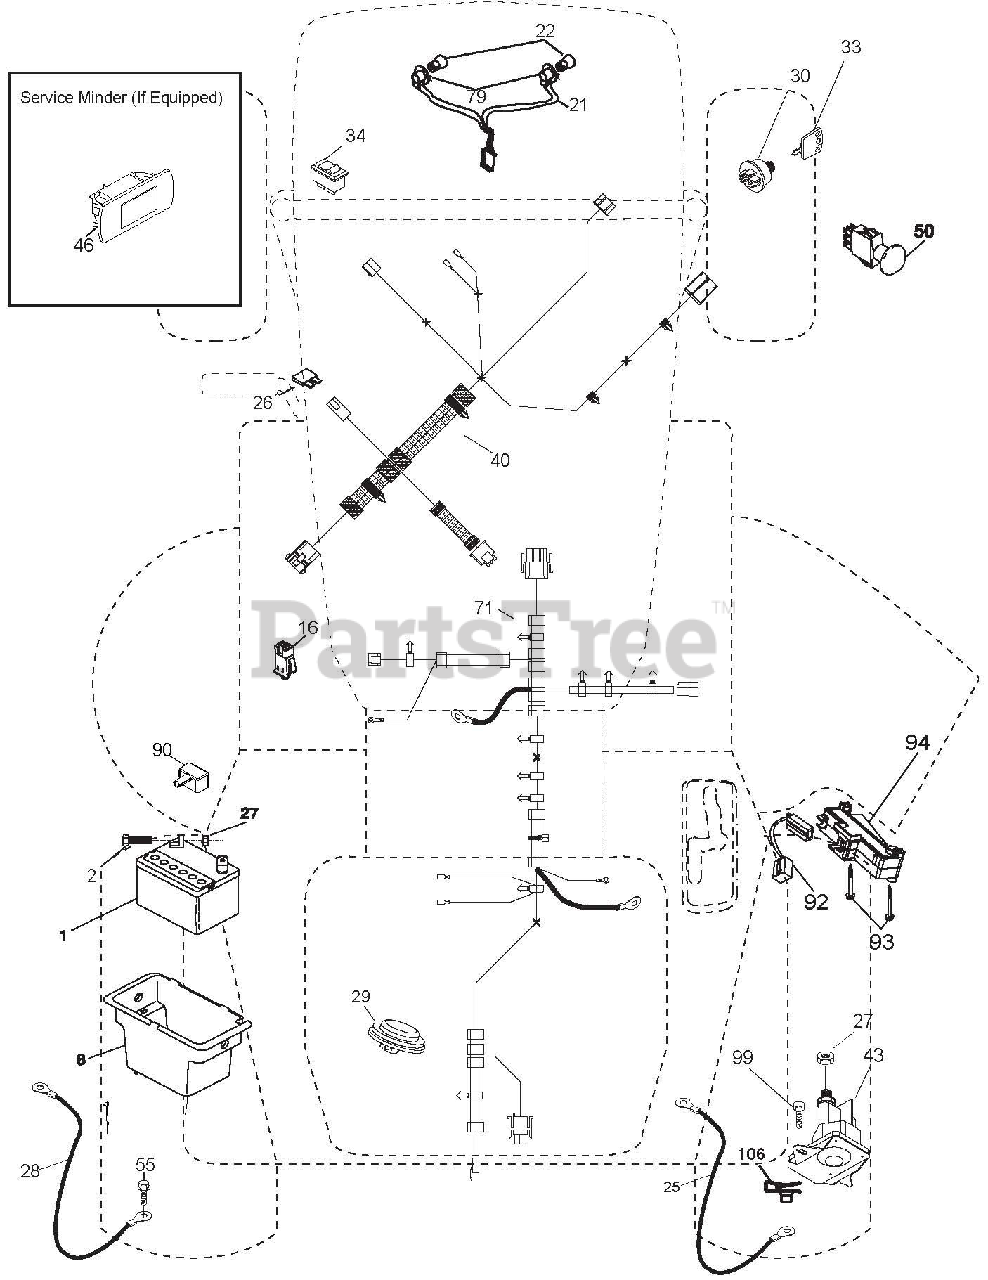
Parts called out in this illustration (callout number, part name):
1	BATTERY.12.VOLT.28.AMP.WET
2	BOLT.HEX.HD.1/4-20UNC X 3/4
8	BOX.BATTERY.MNT.REAR.LT.TEX.BL
16	SWITCH.INTERLOCK.NONO.GRAY
21	HARNESS ASM.LIGHT.22"(4152J)
22	BULB.LIGHT.#1156
25	CABLE STARTER 6 G4. BL/RED14.5
26	FUSE.20 AMP.
27	Nut, Keps Hex 1/4-20 unc
28	CABLE.BLACK.22"REAR BATT.TEX
29	SWITCH.SEAT.DELTA.OPC.9LB.
30	SWITCH.IGN.DLTA.P-IN.ROS
33	KEY/CHAIN.BLISTER PACK.GEN.USA
34	SWITCH.LIGHT/RESET.B/B/RED.
40	HARNESS IGN ELEC RELAY
43	SOLENOID.W/BRASS PLUNGER.2005
46	HOUR METER
50	SWITCH.PTO.8 TERMINAL.BLACK
55	SCREW.5/16-18X3/4.SMGML.TAP/R
71	HARNESS.IGN.CHASSIS.TEX
79	SOCKET ASM.BULB.TWISTLOCK
90	COVER TERMINAL BATTERY FR. TEX
92	HARNESS.PIGTAIL.CONSLE.ROS.MLK
93	SCREW.PLASTITE.10-14 X 2.0
94	MODUAL REVERSE ROS
